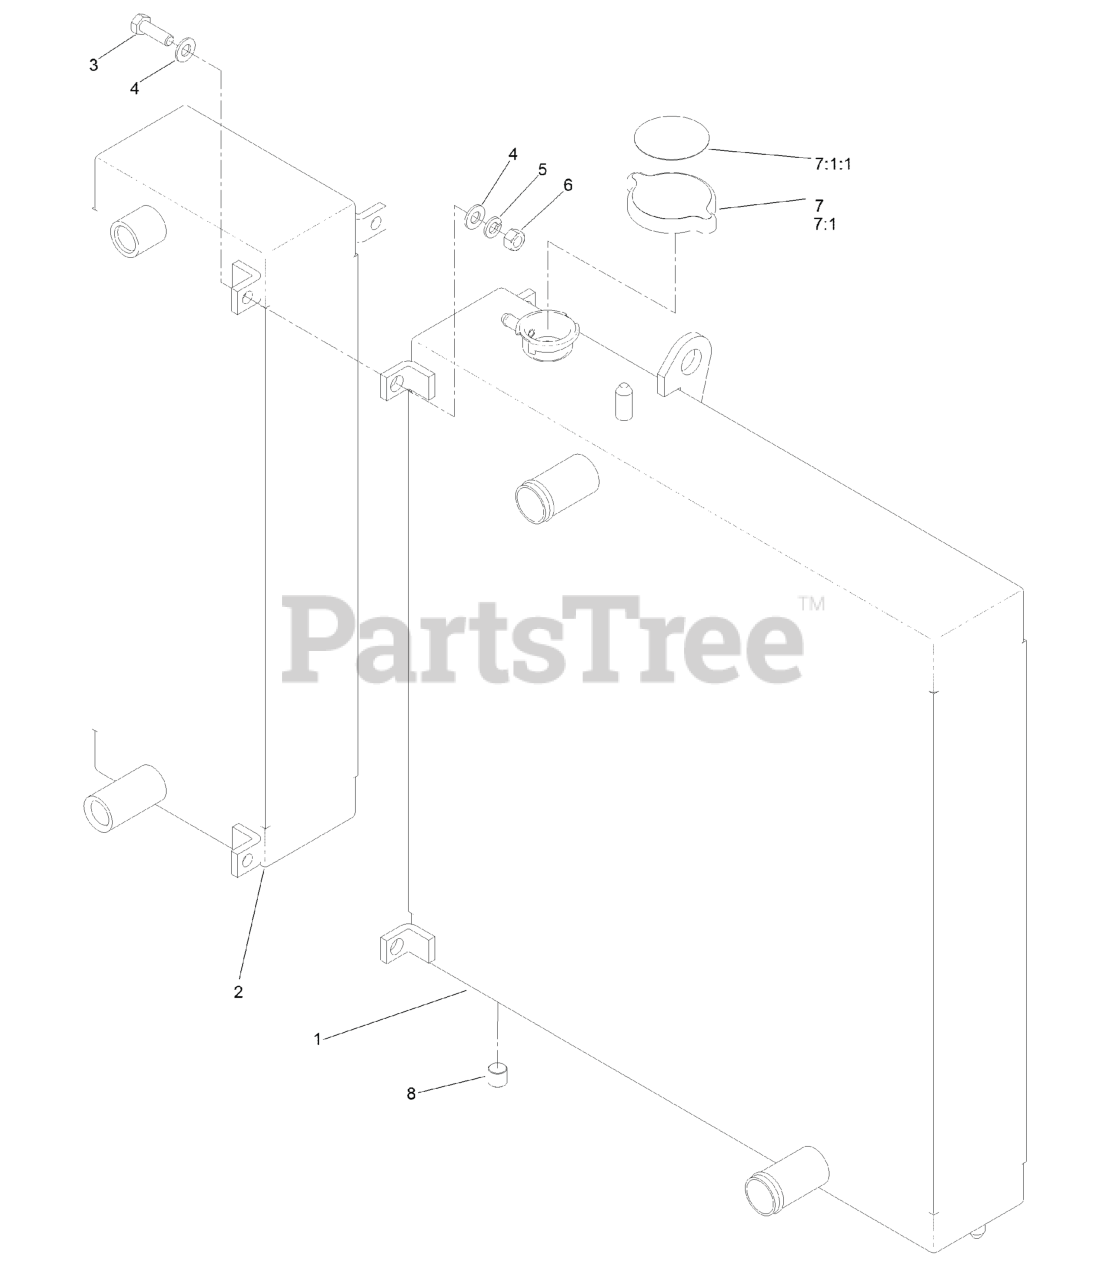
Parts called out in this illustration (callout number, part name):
1	RADIATOR
2	OIL COOLER
3	SCREW-HH
4	WASHER-PLAIN
5	WASHER-LOCK
6	NUT-HEX
7	RADIATOR CAP ASM
7:1	Cap-Radiator
7:1:1	DECAL-DANGER
8	PLUG-PIPE
